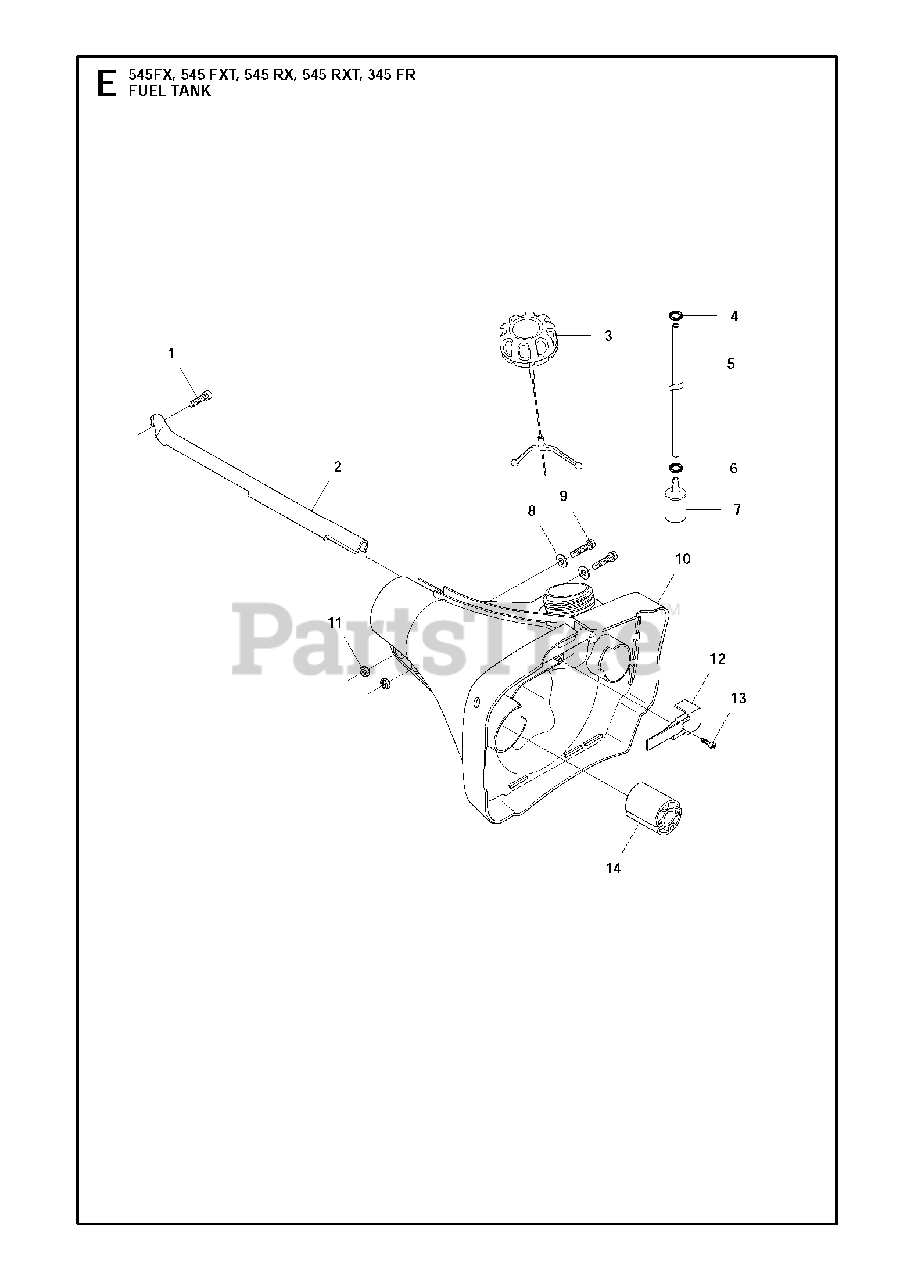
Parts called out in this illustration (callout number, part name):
2	PROTECTOR
3	%WINTER TANK CAP
5	FUEL HOSE STRAIGHT 265
7	FUEL FILTER
8	WASHER 5.3X12
10	TANK UNIT
13	SCREW
14	ANTIVIBRATION ELEMENT
